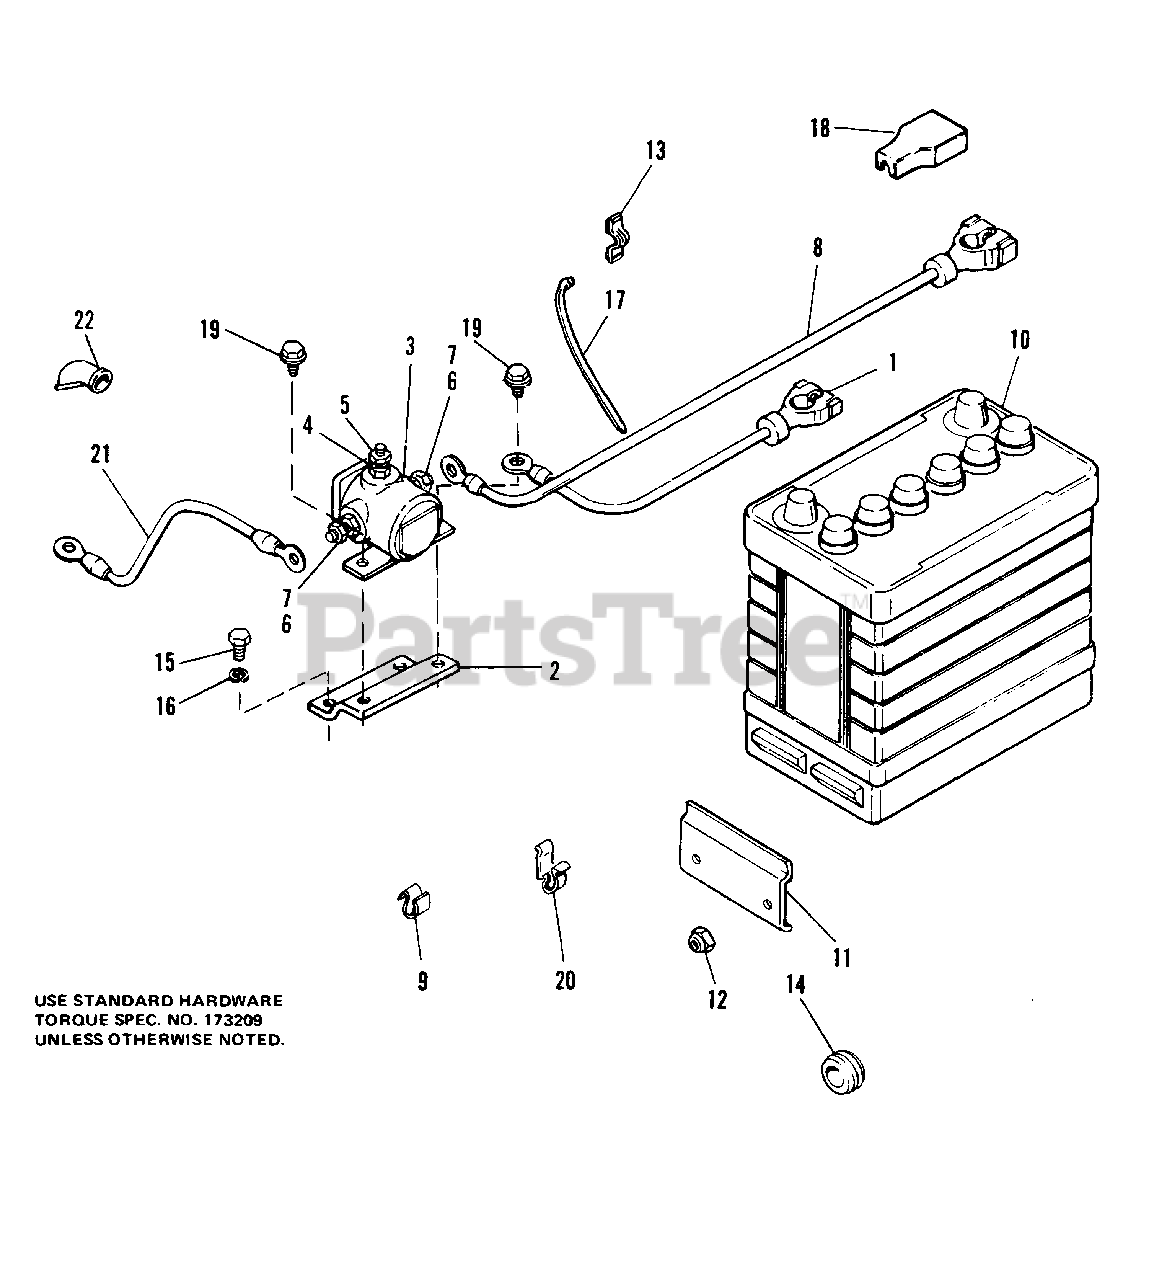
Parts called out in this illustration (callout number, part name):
1	CABLE, Battery to Ground
4	LOCKWASHER, No. 10
5	NUT, Hex, No. 10-32
6	LOCKWASHER, 5/16
7	NUT, Hex, 5/16-18
8	CABLE, Battery to Solenoid
9	CLIP, Tinnerman
12	NUT, Elastic, 5/16-18
13	CLIP, Wire
15	CAPSCREW, Hex Hd., 1/4-20 x 1/2
16	LOCKWASHER, 1/4
17	TIE, Wrap
18	TERMINAL PROTECTOR
19	SCREW, Taptite, 1/4-20 x 3/8
20	CLIP, Tinnerman
21	CABLE, Solenoid to Start
22	COVER, Terminal
